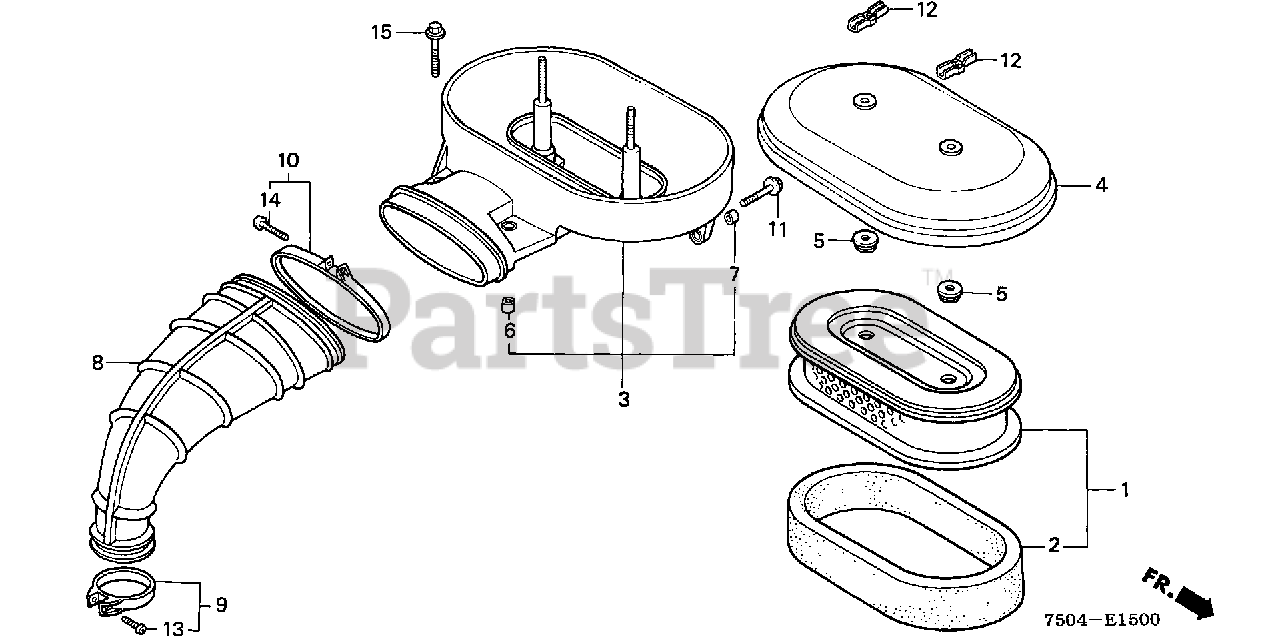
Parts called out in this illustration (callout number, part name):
1	ELEMENT, AIR CLEANER
2	FILTER (OUTER)
3	HOUSING, AIR CLEANER
4	COVER, AIR CLEANER
5	GROMMET, AIR CLEANER
6	COLLAR A, AIR CLEANER
7	COLLAR B, AIR CLEANER
8	TUBE, AIR CLEANER CONNECTING
9	BAND, CONNECTING TUBE
10	BAND ASSY., CONNECTING TUBE
11	BOLT, FLANGE (6X25)
12	WINGNUT, AIR CLEANER COVER
13	SCREW, PAN (4X26)
14	SCREW, PAN (4X25)
15	BOLT, FLANGE (6X35)
